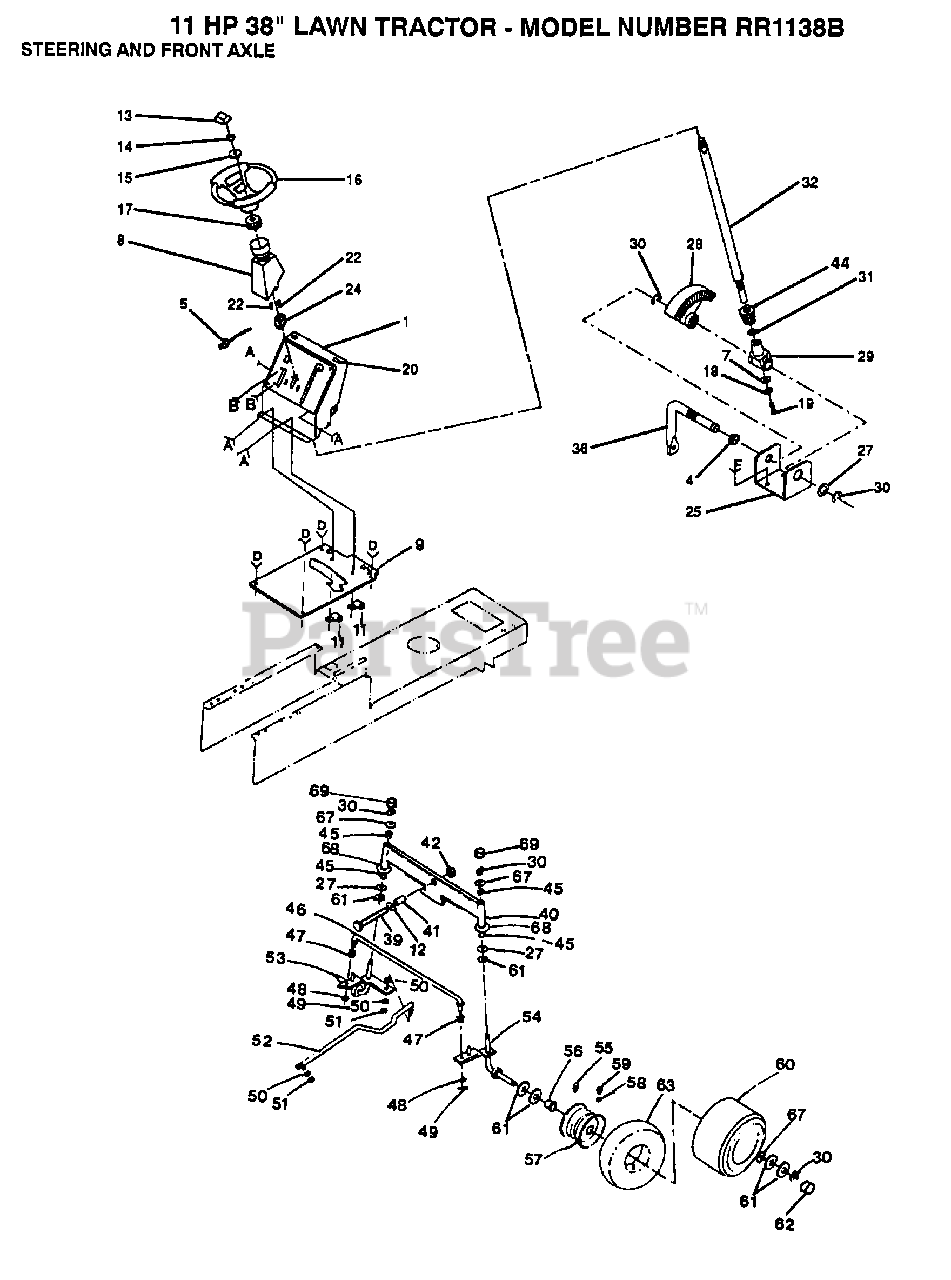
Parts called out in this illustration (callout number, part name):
2	SCREW
4	NYLINER T
6	SCREW LT
8	"TUBE, STR SHAFT"
10	SCREW LT
11	CLIP T
13	INSERT-WHEEL LT
15	WASHER
17	ADAPTER LT
18	LOCKWASHER
19	"SCREW,SPECIAL"
24	"BUSHING,STEERING"
25	"BRKT,STEERING"
26	SCREW
27	WASHER .T
29	SUPPORT.SHAFT
30	RING
31	THRUST WASHER
39	BOLT LT
41	BEARING
42	"NUT-LOC,FLANGE LT"
44	"GEAR,PINION"
45	COL. SRTG. BEAR.
48	WASHER
49	COTTER PIN
50	LOCKWASHER
53	SPINDLE-LH LT
55	FITTING LT
56	"FLANGE, BEARING"
58	VALVE CAP
59	VALVE STEM LT
61	WASHER
62	HUB CAP
63	TUBE.5.3/4.5/6
67	WASHER
68	WASHER
69	CAP
